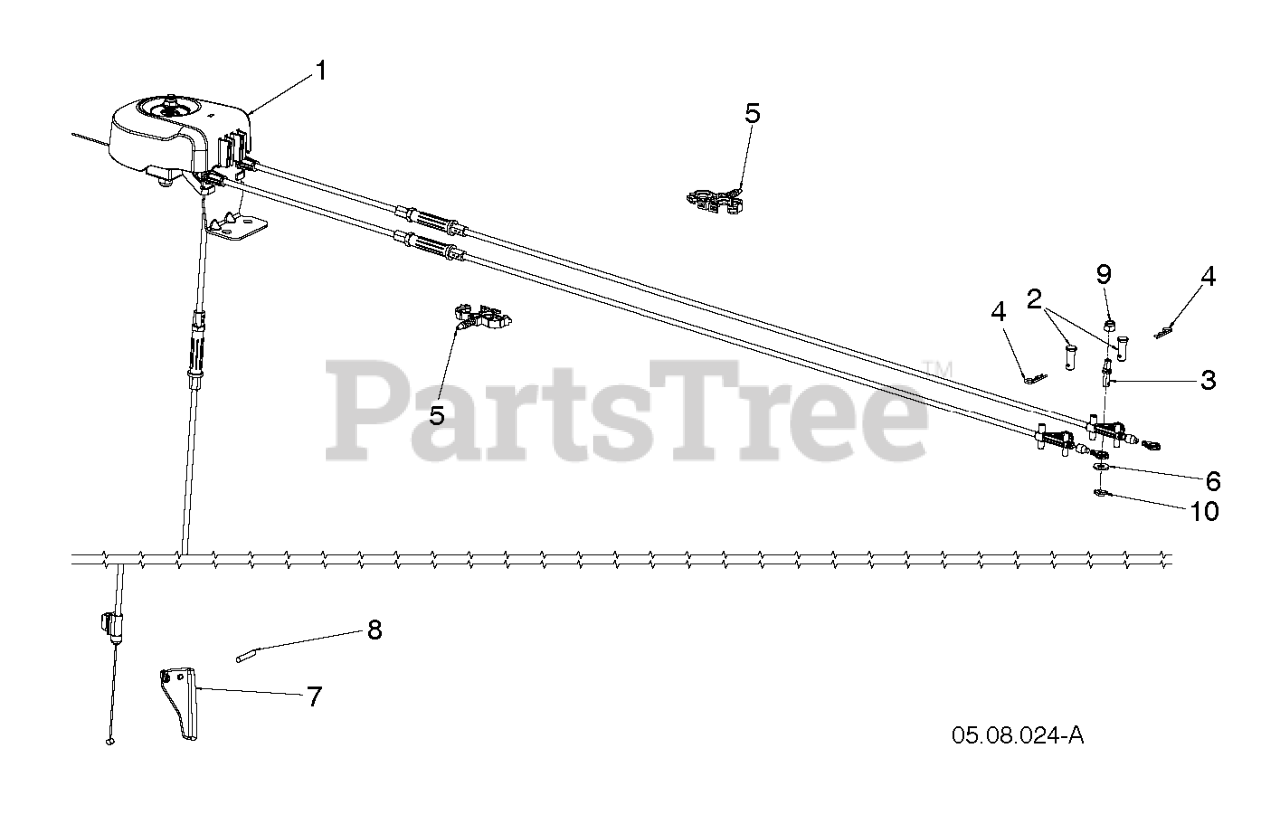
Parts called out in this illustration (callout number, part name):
1	Cables
2	PIN CLEVIS 5/16X.875
3	Pins
4	HAIRPIN.SOFT.ZINC.059X1.125
5	CLIP.CONDUIT.DOUBLE LOOP
6	WASHER FLAT_.250 X .625 X .06
8	PIN, ROLL 3/16 X 1-1/8
9	NUT HEXAGON 1/4-20 ST ZPB
10	GSPW Retainers
